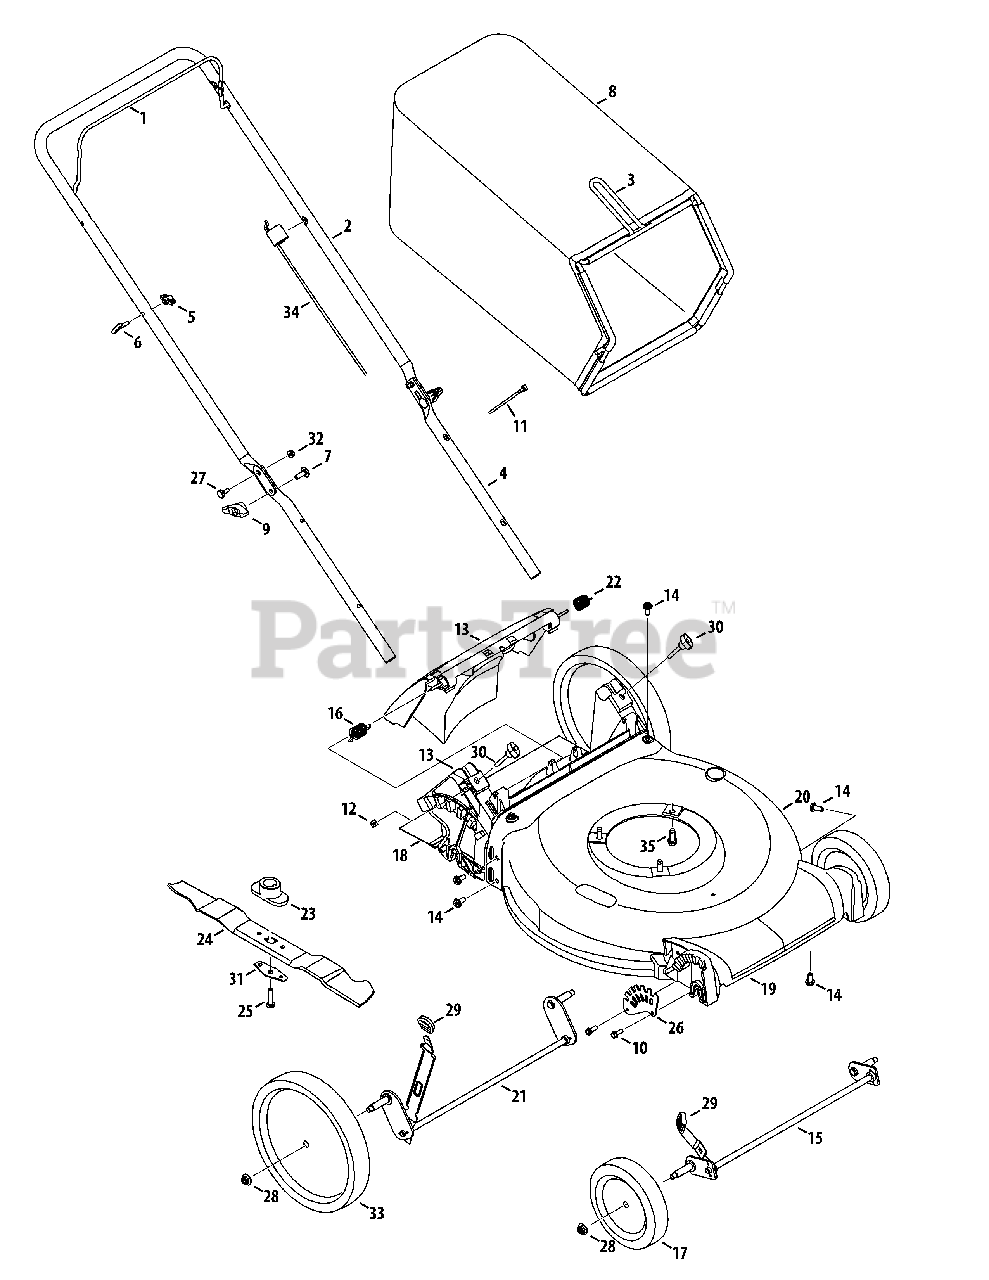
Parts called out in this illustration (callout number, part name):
1	Blade Control
2	Upper Handle
3	Grass Catcher Frame
4	Lower Handle
5	Wing Nut
6	Rope Guide
7	Carriage Screw ,5/16-18
8	Grass Bag
9	Wing Knob
10	Screw, 1/4-15 x .750
11	Cable Tie
12	Nut, Sq., 1/4-20
13	Rear Discharge Door Assembly
14	Screw, 5/16-14 x .750
15	Front Axle Assembly
16	Torsion Spring - RH
17	Front Wheel Gray
18	Trail Shield
19	Front Cover
20	Deck - 21"
21	Rear Axle Assembly
22	Torsion Spring - LH
23	Blade Adapter
24	Mulching Blade
25	Screw , 3/8-24 x 1.50
26	Front Height Adjuster Plate
27	Sldr. Screw, .375 x .126 x 1/4-20
28	Flange Lock Nut, 3/8-16
29	Adjustment Lever Knob
30	Wing Nut
31	Blade Bell Support
32	Nut, Flange Lock, 1/4-20
33	Rear Wheel
34	Control Cable
35	TT Sems Screw, 3/8-16 x 1.0
